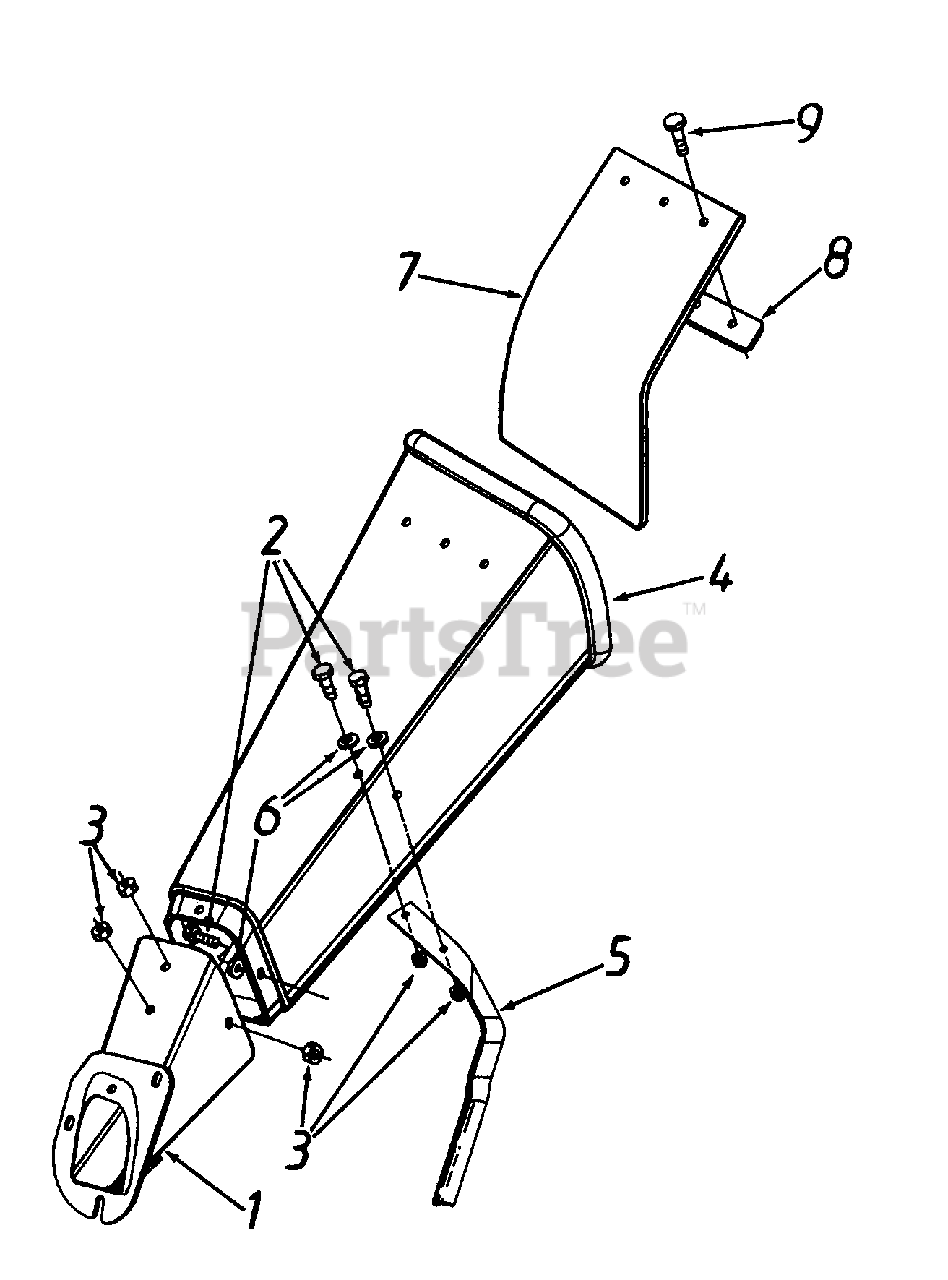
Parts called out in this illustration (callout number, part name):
3	NUT-LOCK
4	CHUTE-CHIPPER UPPER
5	FL-WASH. .28" I.D. x .73" O.D.
8	STRIP-FLAP
9	RIVET
